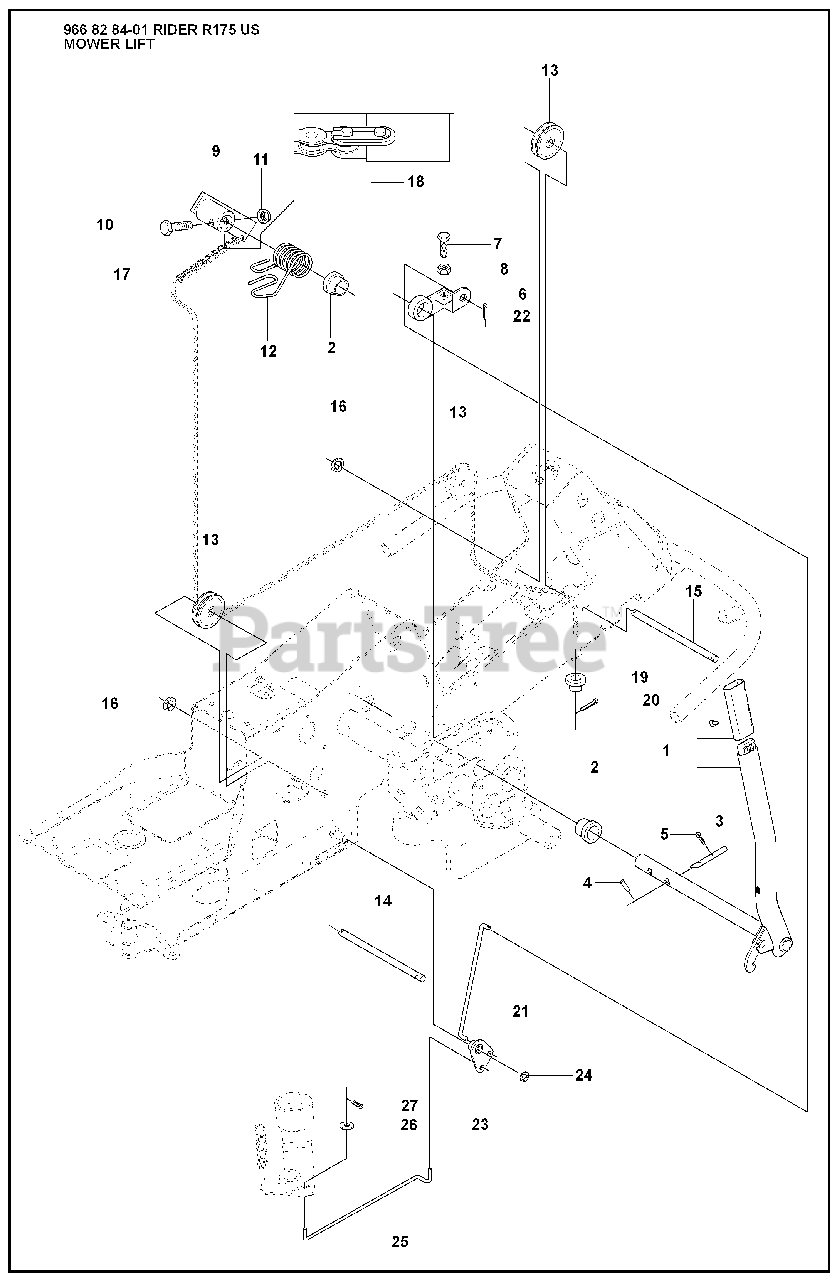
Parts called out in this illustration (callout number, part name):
1	LIFTING LEVER ASSY
2	BEARING FLANGE
3	RP PIN
6	LEVER CLUTCH
8	NUT
11	Lock Nut, Fiber M12 DIN 985 Z/P
20	COTTER PIN
21	CONNECTION ROD
24	RETAINING RING
25	CONNECTION ROD
